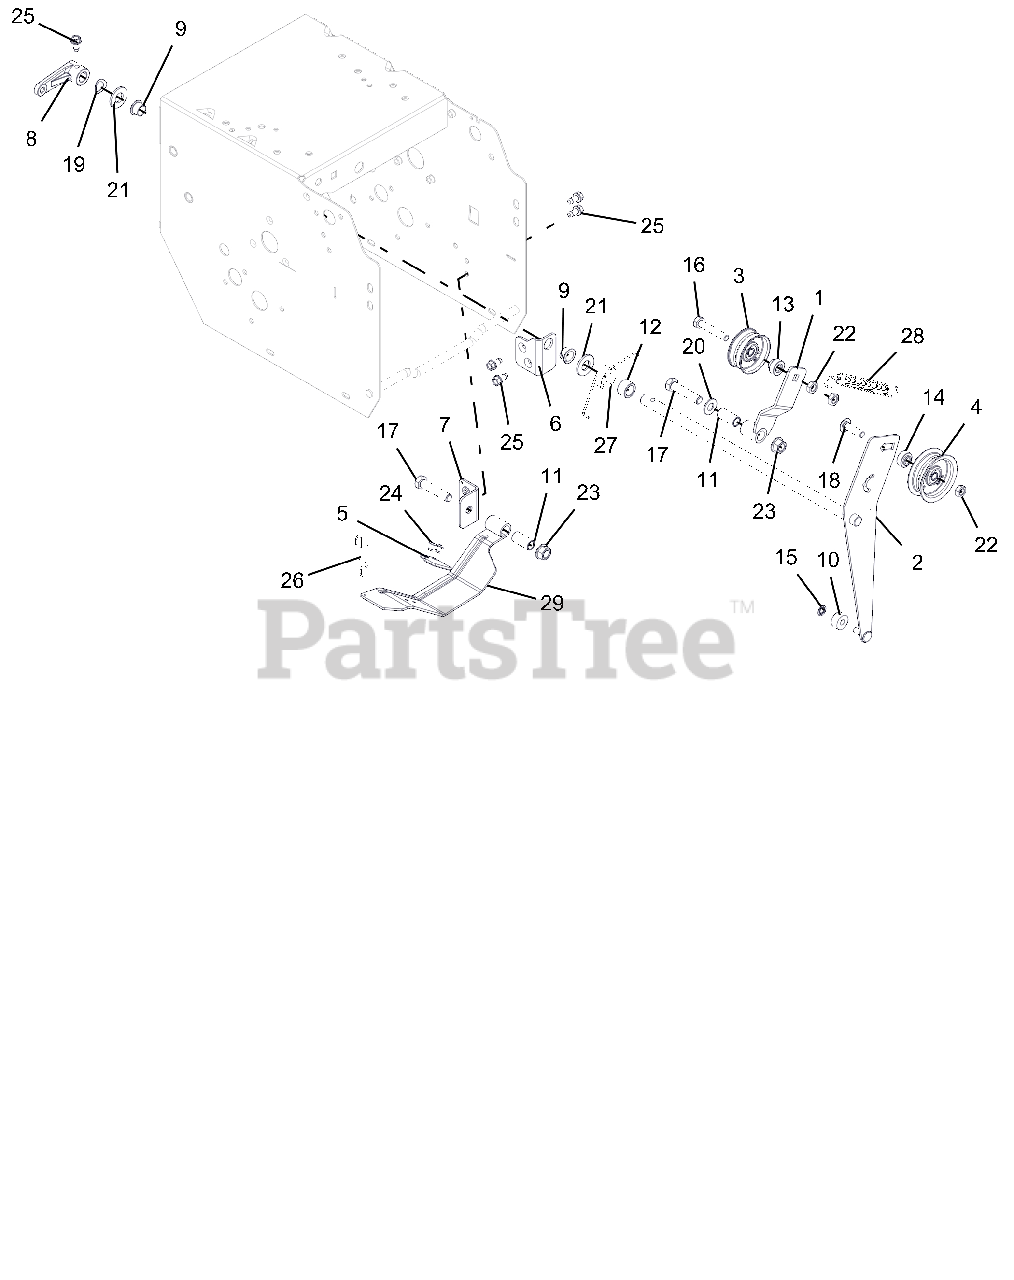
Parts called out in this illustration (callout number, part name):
1	ARM, TRACTION IDLER
2	WELDMENT, ATTACHMENT IDLER ARM
3	IDLER, FLAT - 1.875"
4	IDLER, FLAT - 2.00"
5	PAD, BRAKE
6	BRACKET, MOUNT - IDLER ARM
7	BRACKET, MOUNT - BRAKE
8	ARM, CLUTCH - ATTACHMENT
9	BUSHING, POLYLINER-.50 SPLIT
10	BSHG,SLV .265 X .625 X .375
11	BSHG-SLV .385X.500X1.045
12	BSHG-SLV .510X.751X.475
13	SPCR, BRG .315X.500X.481X.281
14	SPCR, BRG .315X.500X.358X.281
15	RG-RTNG-EXT .250X.010
16	@BLT-HEX .31-18X1.75 GR5 YWZC
17	@BLT-HEX .38-16X1.75 GR5 YWZC
18	BLT-RDHDSQSHNK.31-18X1.13 G5YZ
19	WSHR-WAVE .50X.75X.015 .13FRHT
20	@WSHR-FL-STL.406X.812X.065 YWZ
21	@WSHR-FL-STL.531X1.06X.095YWZC
22	@NUT-LK-CTR-JAM .31-18 YWZC
23	@NUT-LK-TOP-FLG .38-16 YWZC
24	RVT-POP .187 YZ
25	SCR-TAP .25-20X.50 HWH TR YWZ
26	SPRING-EXT .437 X .438 X 2.64
27	SG-TORS .075 X .955
28	SPRING, SWIVEL HOOK EXTENSION
29	BRAKE ARM W/PAD
